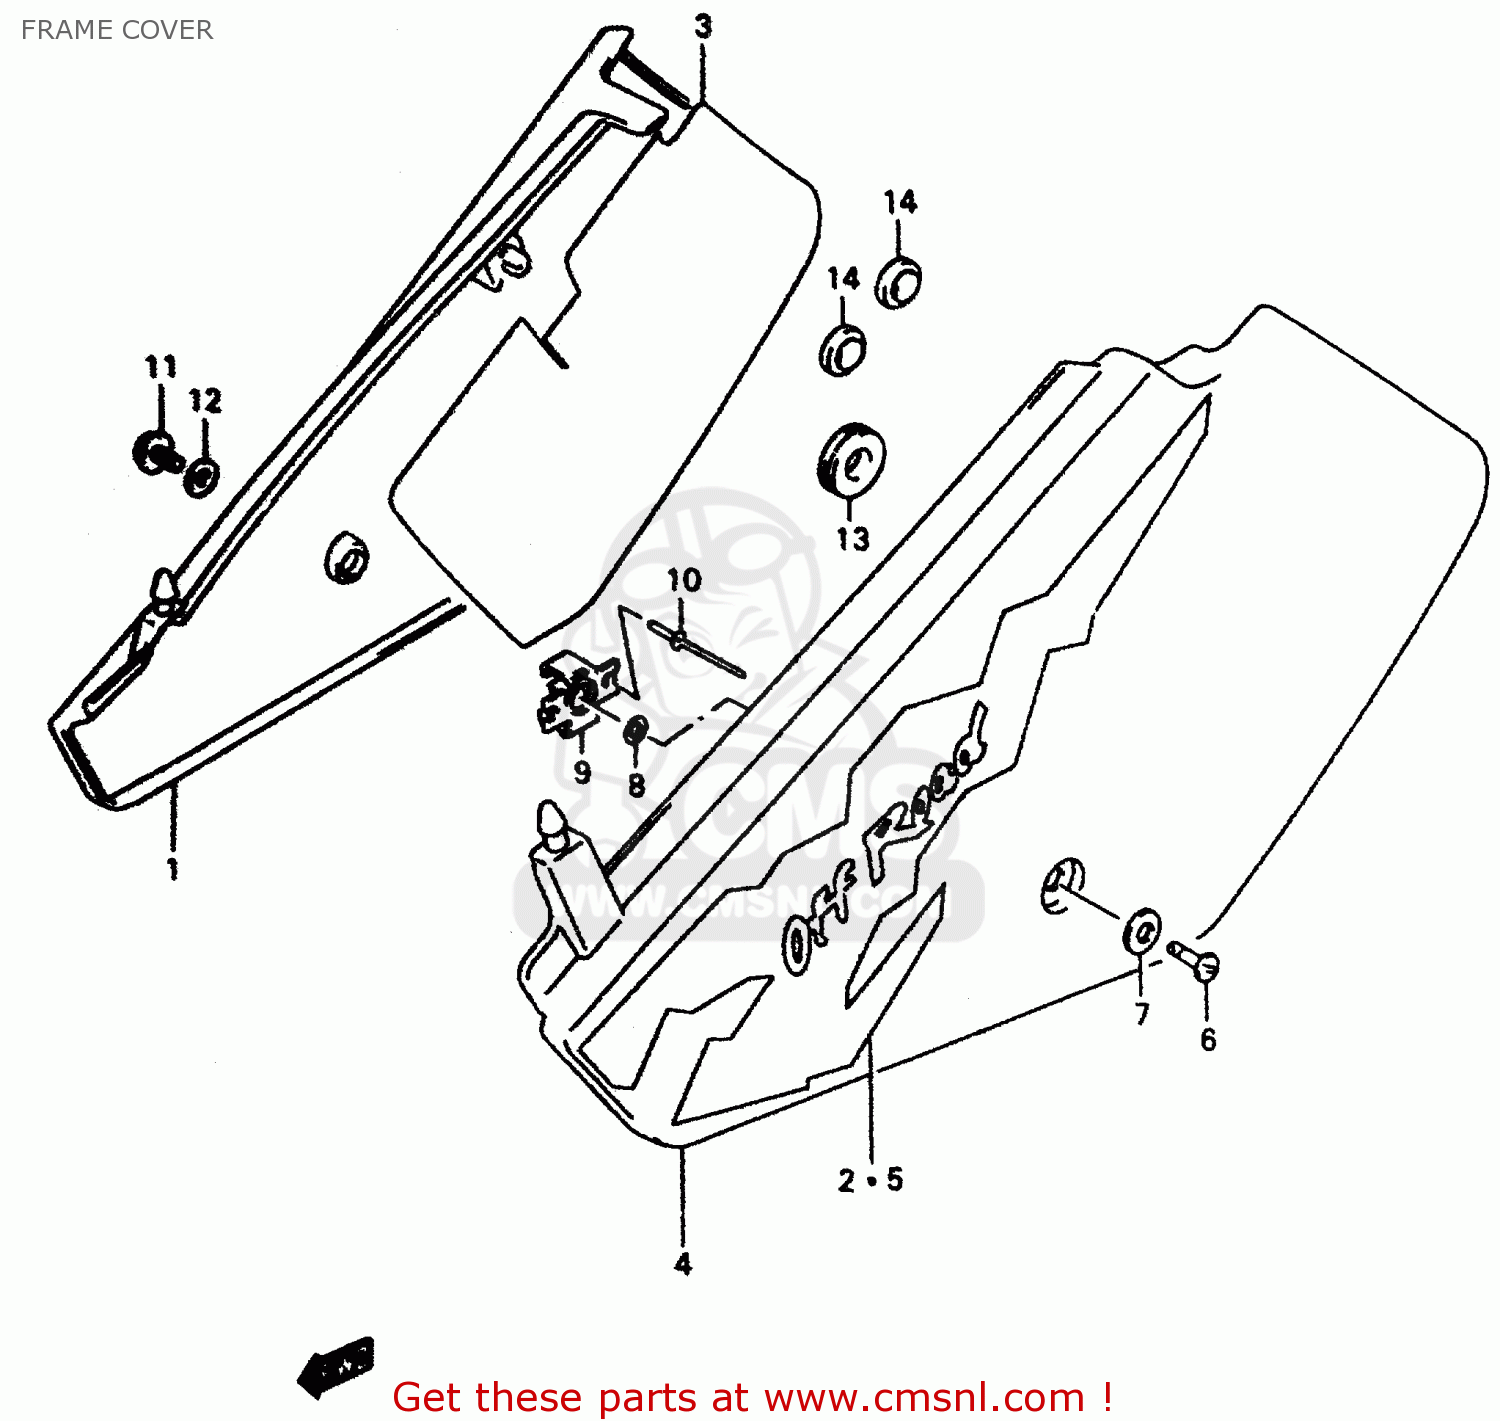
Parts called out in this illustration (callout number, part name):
1	COVER,FRAME,R(WHITE)
2	TAPE,FRAME COVER,RIGHT
3	SHIELD,FRAME COVER,R
4	COVER,FRAME,L(WHITE)
5	TAPE,FRAME COVER,L
6	STUD,FRAME COVER,LEFT
7	WASHER
8	RETAINER,FRAME COVER STUD,L
9	PLATE,FITING
10	RIVET
11	SCREW
12	WASHER
13	CUSHION
14	CUSHION
